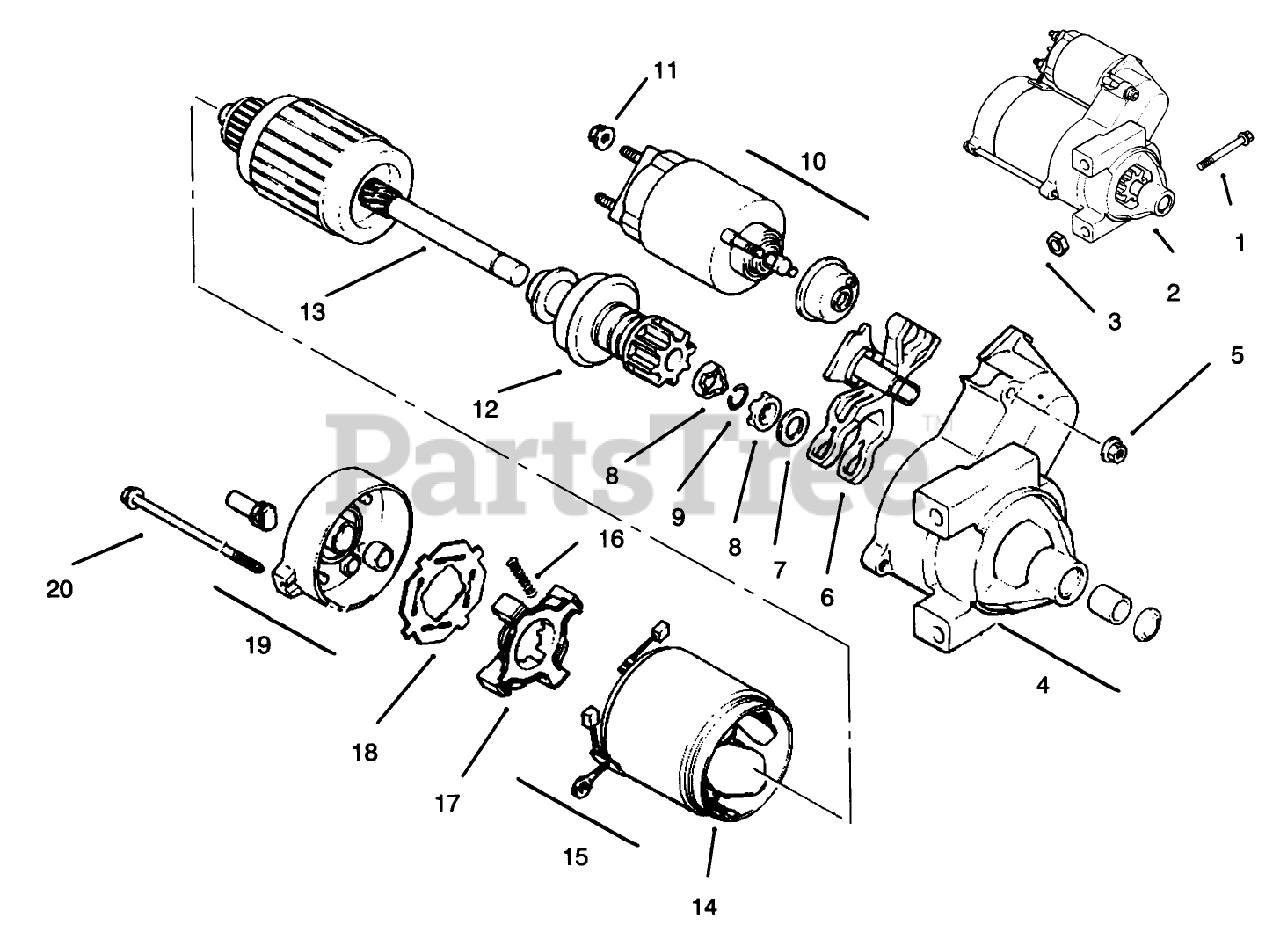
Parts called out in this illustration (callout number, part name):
2	Starter-Solenoid Shift (Incl. Ref. # 4-20)
4	Cap-Drive End
5	Nut Starter
6	Lever Starter Drive
7	Washer-Thrust
8	Nut-Stop Collar
9	Ring-Retainer
10	Solenoid
12	Drive-Pinion
13	Armature-Starter
15	Kit-Brush (Incl. Ref. # 16)
16	Spring-Brush
17	Holder-Brush
18	Insulator
19	Cap-Commutator End
